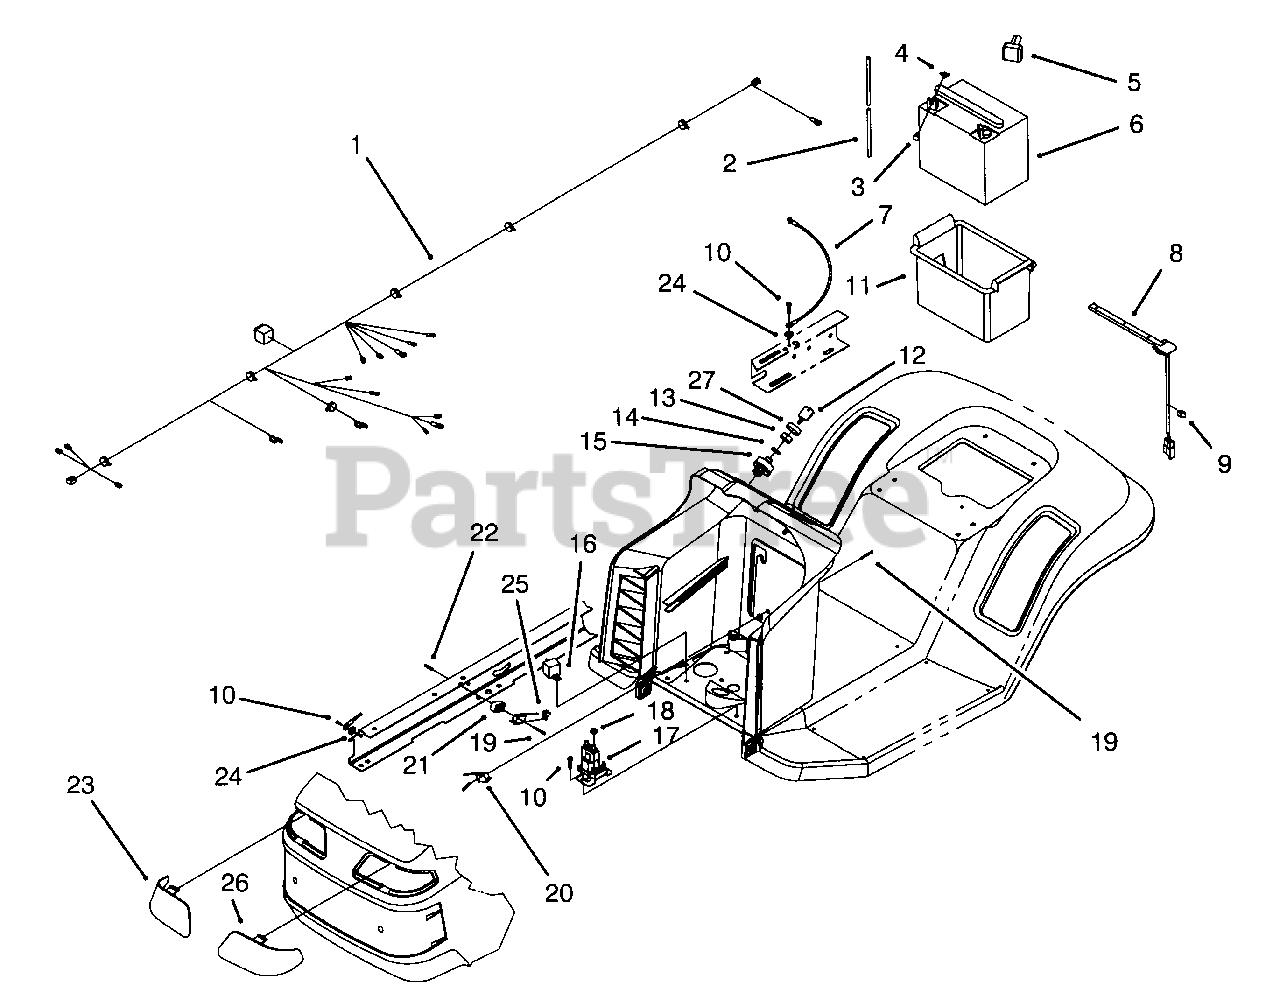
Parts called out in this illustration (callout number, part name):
1	Harness-Wire
2	Vent-Tube
3	Screw-Hex Hd. Cap
5	Boot-Battery Terminal
6	Battery-7 Plate
7	Cable-Battery Negative
8	Switch-Seat
9	Clip-Wire Retainer
10	Screw-Hex Hd. Thr'd Forming
11	Box-Battery
12	Key-Ignition
14	Washer-Lock
15	Switch-Ignition (Incl. Ref. #13 & 14)
17	Solenoid
18	Nut-Keps
19	Screw-Phillips Hd.
20	Switch-Micro
21	Spacer-Microswitch
23	Lens-R.H.
24	Washer-Ext. Tooth Lock
25	Seal-Plunger
26	Lens-L.H.
